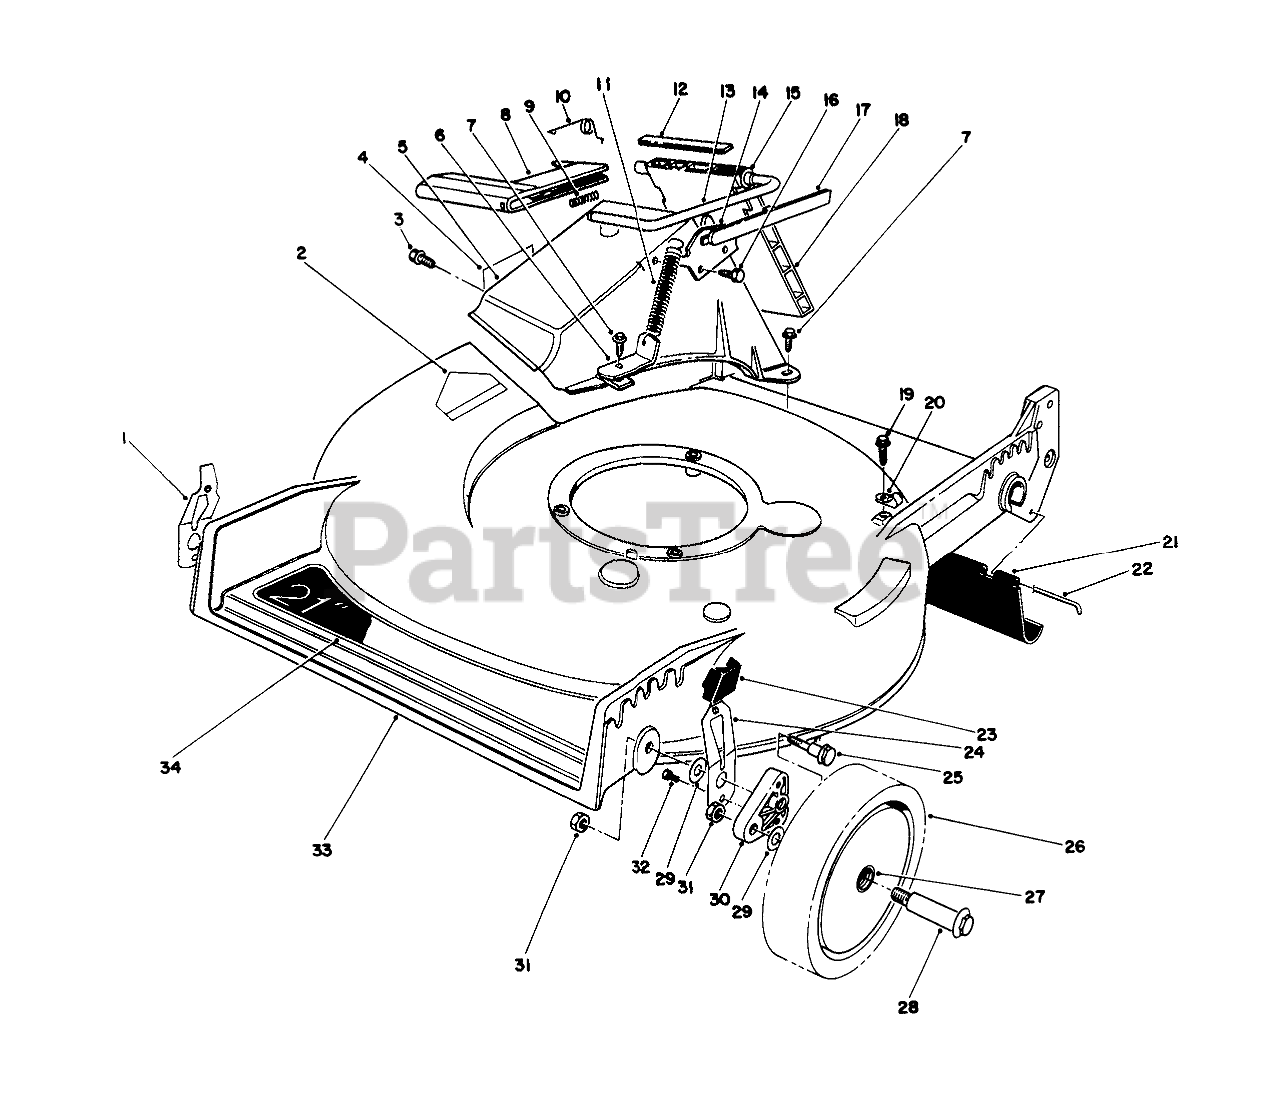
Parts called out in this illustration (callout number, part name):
1	RH SPRING ARM ASSEMBLY
2	DECAL-DANGER
3	SCREW AND WASHER ASM
4	DECAL - DANGER
5	Tunnel-Discharge (Incl. Ref. #4)
6	Bracket-Spring
7	SCREW-HWH
8	Handle-Door
9	Spring
10	RETAINER-DOOR
11	SPRING-DOOR
12	Cover-Door
13	Rod-Door
14	DOOR LATCH PLATE
15	BUSHING-NYLON
16	SCREW-PLASTITE
17	Cover-Handle
18	Door-Discharge
19	SCREW-HWHTF
20	CLAMP-R
21	SHIELD-TRAILING
22	ROD-SHIELD
23	KNOB-ARM
24	LH SPRING ARM ASSEMBLY
25	SCREW-SHOULDER
26	Wheel & Tire Assembly (Incl. Ref. #27)
27	BUSHING
28	WHEEL BOLT
29	WASHER
30	ARM-PIVOT, FRONT
31	Nut
32	SCREW-HWH
33	Housing Assembly (Incl. Ref. #2)
34	DECAL - DECK
